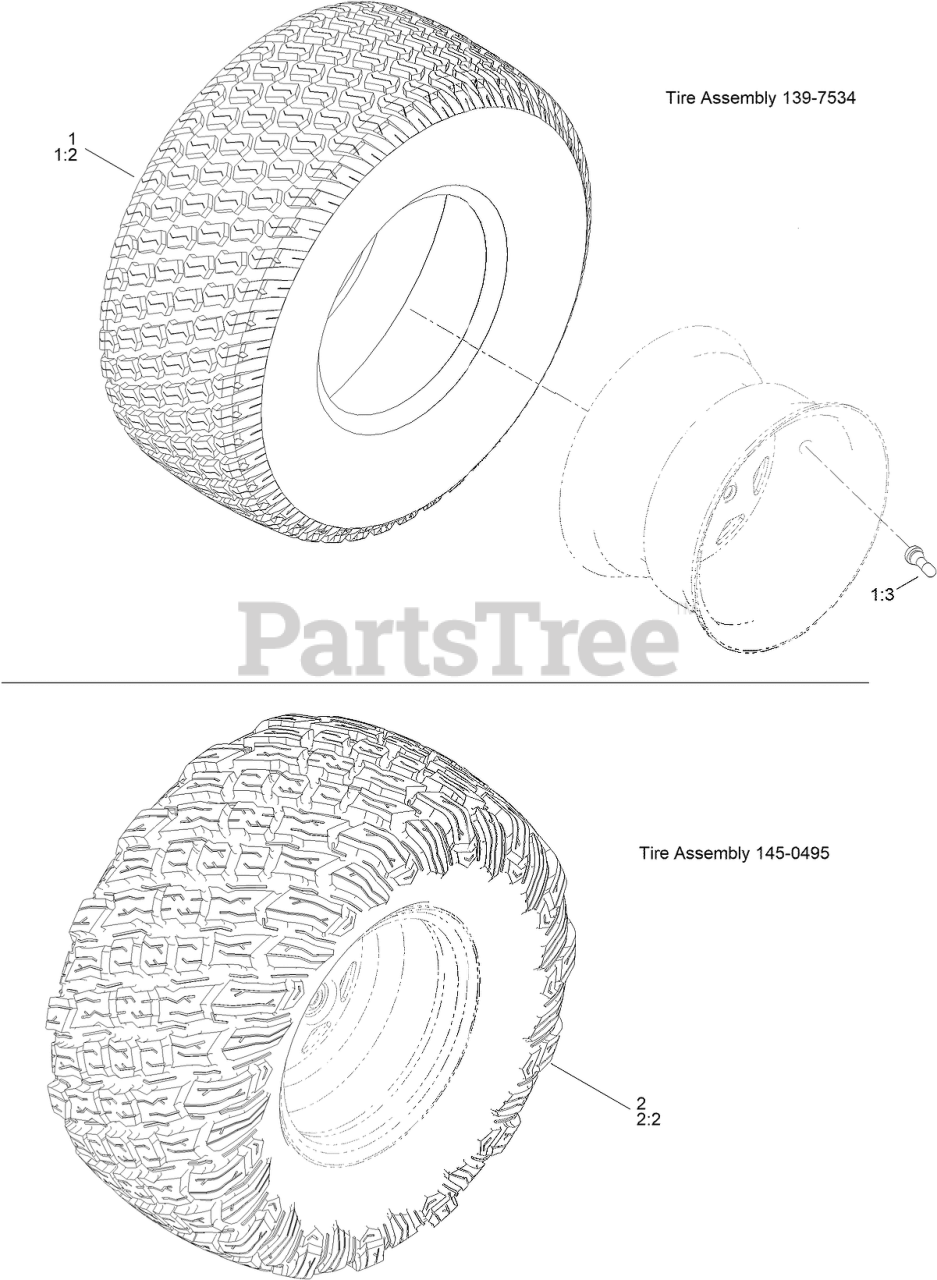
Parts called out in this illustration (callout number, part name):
1	TIRE AND WHEEL ASM
1:99	TUBE-INNER
2	TIRE ASM
